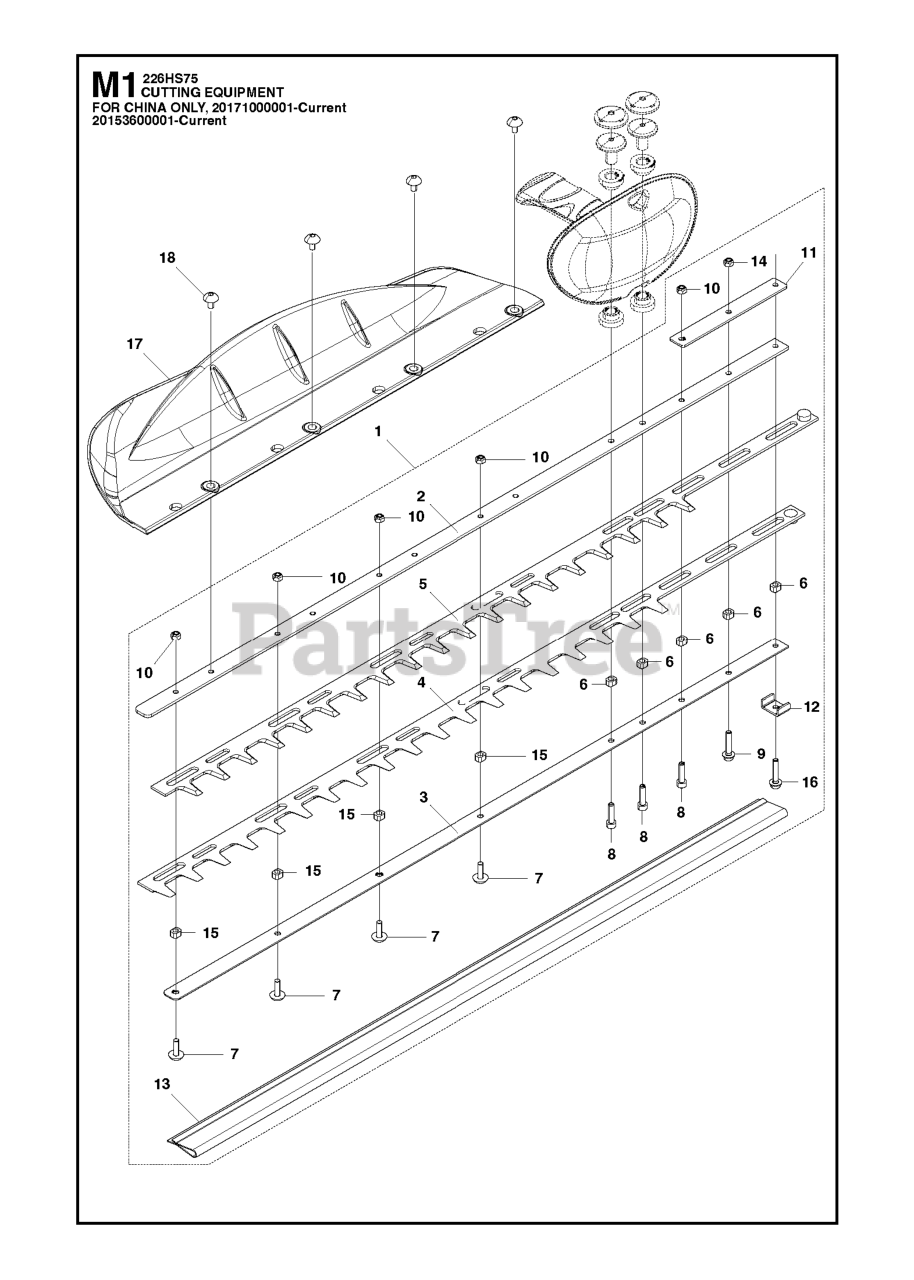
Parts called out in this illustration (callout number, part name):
2	PLATE,UPPER
3	PLATE,LOWER
4	BLADE,LOWER
5	BLADE,UPPER
8	BOLT
9	BOLT TORX M5XL35
13	COVER, BLADE
